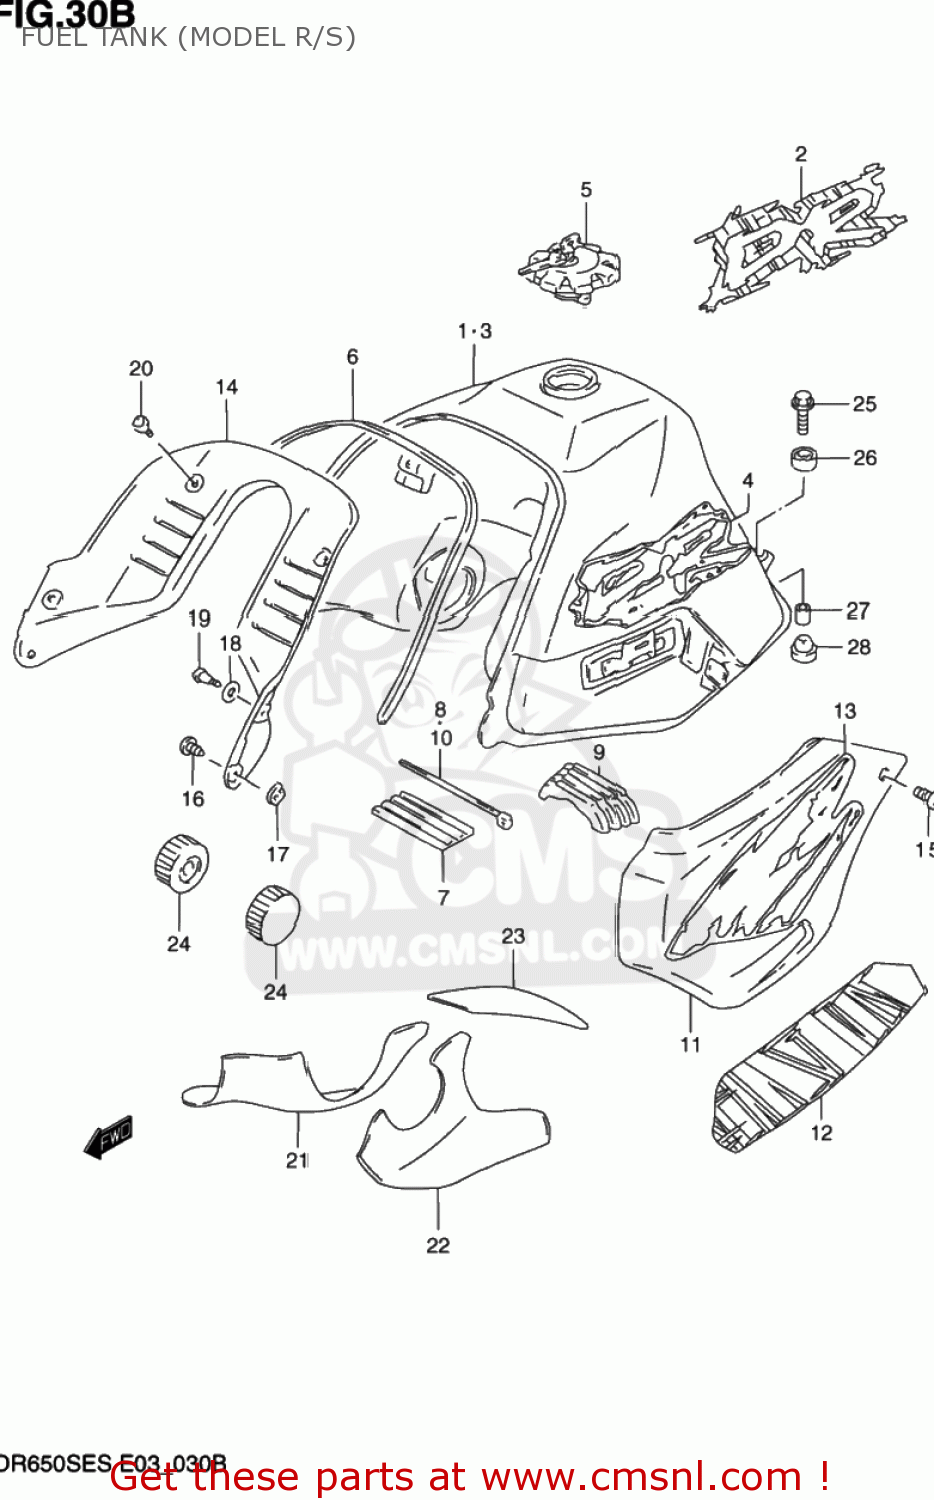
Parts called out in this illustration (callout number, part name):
1	TANK ASSEMBLY,FUEL
2	EMBLEM SET,FUEL TANK
3	TANK ASSEMBLY,FUEL
4	EMBLEM SET,FUEL TANK
5	CAP SET,FUEL TANK
6	MOLDING,FUEL TANK
7	CUSHION,FUEL TANK UPR FR
8	CLAMP
9	CUSHION,TANK UPR RR
10	CLAMP(L:300)
11	COVER,FUEL TANK,R
12	TAPE,TANK COVER,R
13	TAPE,TANK COVER,LEFT
14	COVER,FUEL TANK,FRONT
15	SCREW
16	SCREW
17	NUT
18	WASHER (5.1X20X1.4)
19	SCREW(5X18)
20	SCREW
21	SHIELD,FUEL TANK,RIGHT
22	SHIELD,FUEL TANK,LEFT
23	SHIELD,FUEL TANK,CENTER
24	CUSHION,FUEL TANK FR
25	BOLT
26	CUSHION
27	SPACER
28	CUSHION
